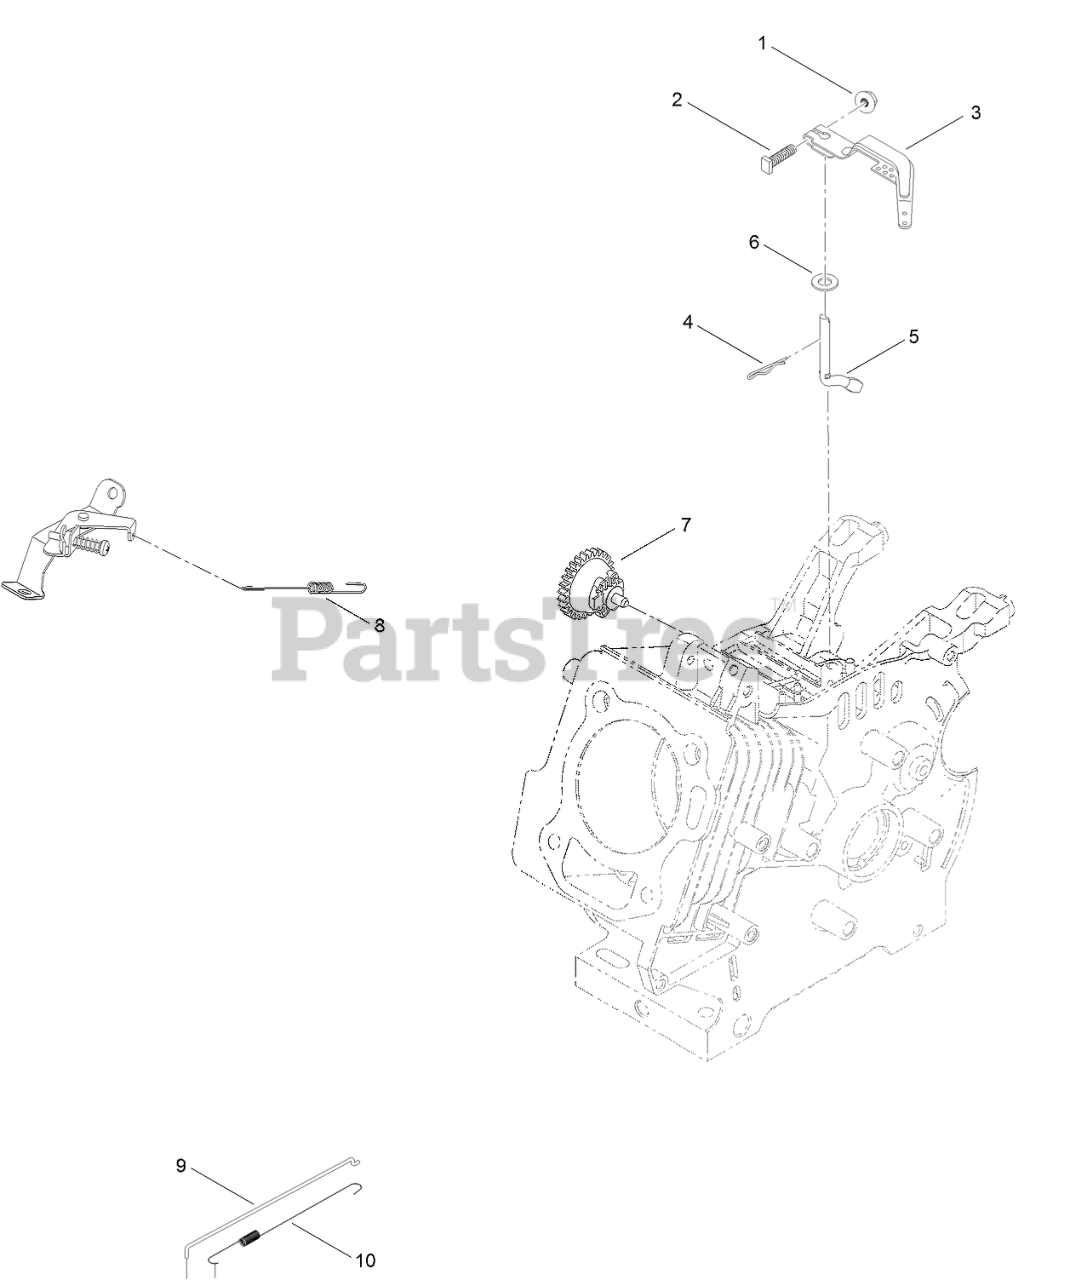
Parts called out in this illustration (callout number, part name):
1	NUT-FLANGE
2	BOLT-ARM, GOVERNOR
3	ARM-GOVERNOR
4	PIN-HAIR
5	SHAFT-GOVERNOR
6	WASHER-PLAIN
7	GOVERNOR GEAR ASM
8	SPRING-GOVERNOR
9	ROD-GOVERNOR
10	SPRING-RETURN, THROTTLE
